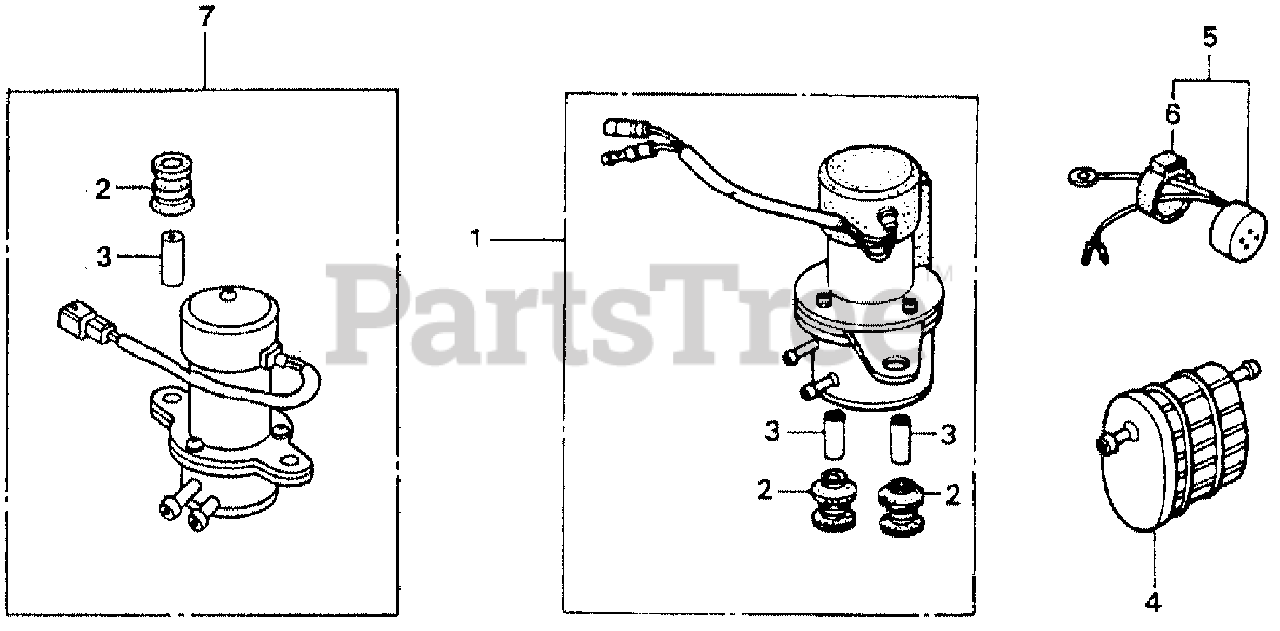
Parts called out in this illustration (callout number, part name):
1	PUMP ASSY., FUEL (CONNECTOR)
1	PUMP ASSY., FUEL (MITSUBISHI)
2	RUBBER, FUEL PUMP SETTING
3	COLLAR, DISTANCE
3	COLLAR, FUEL PUMP DISTANCE
4	FILTER, FUEL
5	BUZZER ASSY.
6	SUSPENSION, AUDIBLE PILOT
